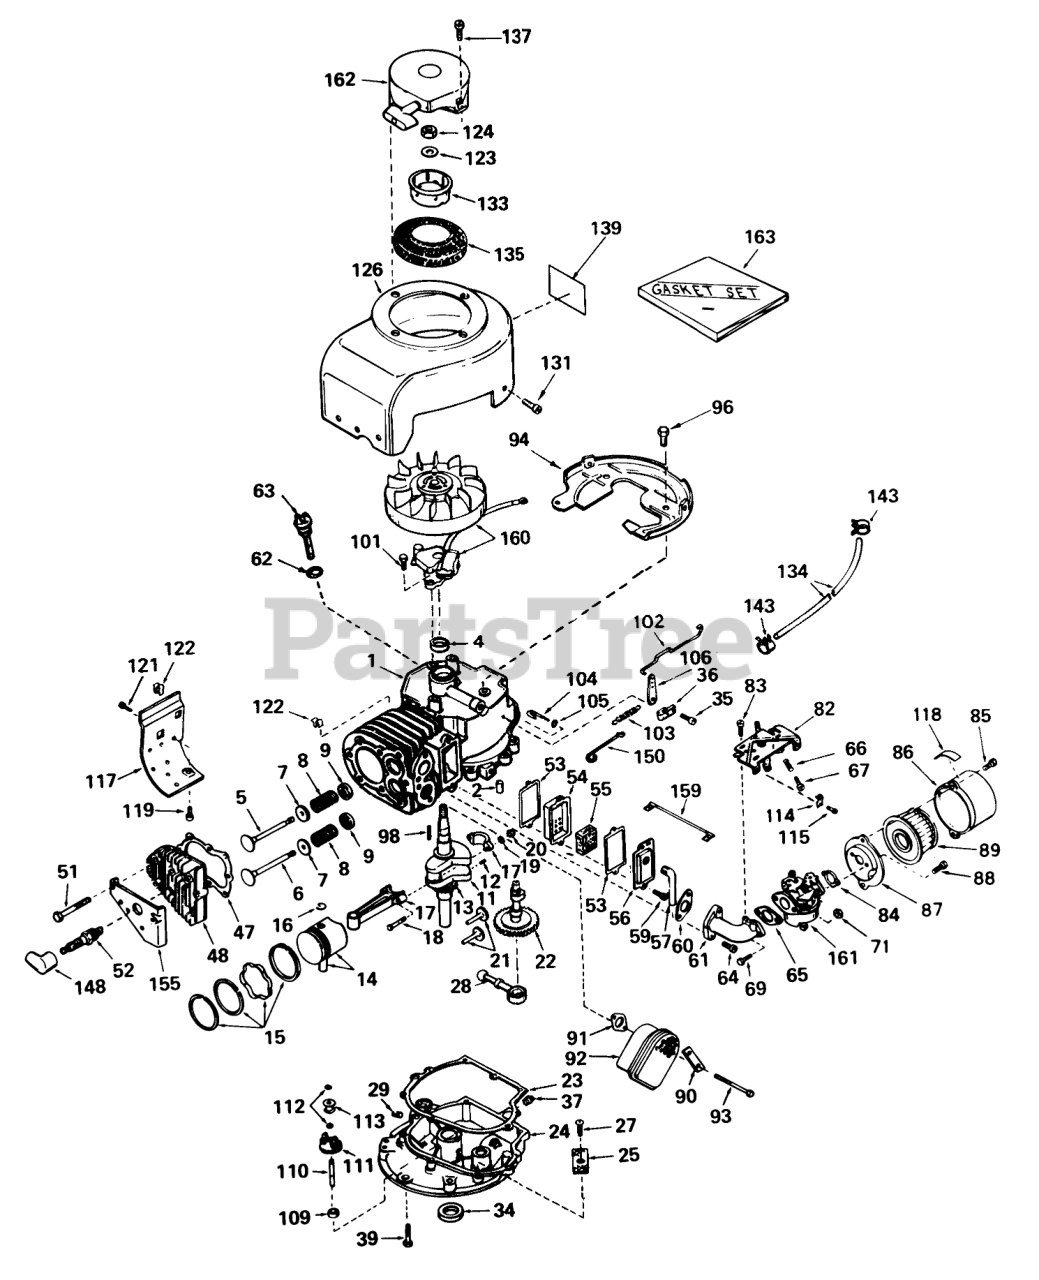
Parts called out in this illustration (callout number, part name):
1	Cylinder Assy. (Incl. # 2, 4, 5 & 63)
2	Pin-Dowel
4	Seal, Oil
5	Valve, Intake (Std.)(Incl. #9)
5	Valve, Intake (1/32" Oversize)(Incl. # 9)
6	Valve, Exhaust (Std.)(Incl. #9)
6	Valve, Exhaust (1 /32" Oversize (Incl. #9)
7	Cap-Spring, Valve
8	Spring-Valve
9	Keeper-Spring, Valve
11	Crankshaft Assy. (Incl. # 12 & 13)
12	Pin, Groove
13	Gear-Crankshaft
14	Piston & Pin Assy. (Incl. 2 of # 16)(Std.)
14	Piston & Pin Assy. (.010 Oversize)(Incl. 2 of # 16)
14	Piston & Pin Assy. (.020 Oversize)(Incl. 2 of # 16)
15	Ring Set, Piston (Std.)
15	Ring Set, Piston (.010 Oversize)
15	Ring Set, Piston (.020 oversize)
16	Ring-Retaining, Piston Pin
17	Rod Assy., Connecting (Incl. # 18, 19 & 20)
18	Bolt, Connecting Rod
21	Lifter-Valve
23	Gasket-Cover, Cylinder
24	Flange Assy., Mounting (Incl. #25, 27, 34, 37 & 110)
25	Screen-Oil Filter
28	Pump, Oil
29	Plug-Pipe (Internal Hex, 1/4-18)
34	Seal-Oil
35	Screw
36	Clamp-Lever, Governor
37	Plug-Drain, Oil (SQH 1/4-18)
39	Screw (1/4-20 x 1-1/4)
47	Gasket-Head, Cylinder
48	CYLINDER HEAD
51	Screw Hex Hd. Cap
52	Plug, Spark (Champion RCJ-8)
53	Gasket-Breather
54	Body-Breather
55	Element-Breather
56	Cover-Valve
57	Tube-Breather
60	Gasket-Intake
61	Pipe, Intake
62	Gasket
63	Dipstick, Oil (Incl. # 62)
64	Screw (T-30, 5/16-18x1-3/32)
65	Gasket
66	Spring-Compression
67	Screw
69	Screw (1/4-28 x 7/8)
71	Nut and Lock Washer (1/4-28)
82	Control Assembly, Speed (Incl. # 66 & 67)
83	Screw (10-24 x 9/16)
84	Gasket
86	Body
87	Bracket
88	Screw (10-32 x 1/2)
89	Element
90	Plate-Locking
91	Gasket Exhaust
92	Muffler
93	Screw Hex Hd.
94	Baffle Blower Housing
96	Screw (1/4-20x19/32)
98	Key, Flywheel
102	Link Governor
103	Spring Governor
104	Rod, Governor (Incl. # 105)
105	Washer-Flat
106	Lever-Governor
109	Spacer
110	Shaft, Governor
111	Governor Gear ASM
112	Ring-Retaining
113	Spool-Governor
114	Conduit
115	Screw (10-32 x 3/8)
117	Emnsion, Blower Housing
121	Screw
122	51004 GIL ROTARY TI
123	Washer
126	Housing, Blower
131	Screw, Hex Hd.
133	Cup-Starter
134	Line-Fuel
135	Screen, Air
139	480B GIL SNWTHWR O/
143	Clamp-Line, Fuel
148	Cover-Spark Plug
150	Link Governor Spring
155	Cover-Head, Cylinder
159	Wire, Ground
161	Carburetor (Incl. # 65)
162	Starter, Rewind
163	Gasket Set
